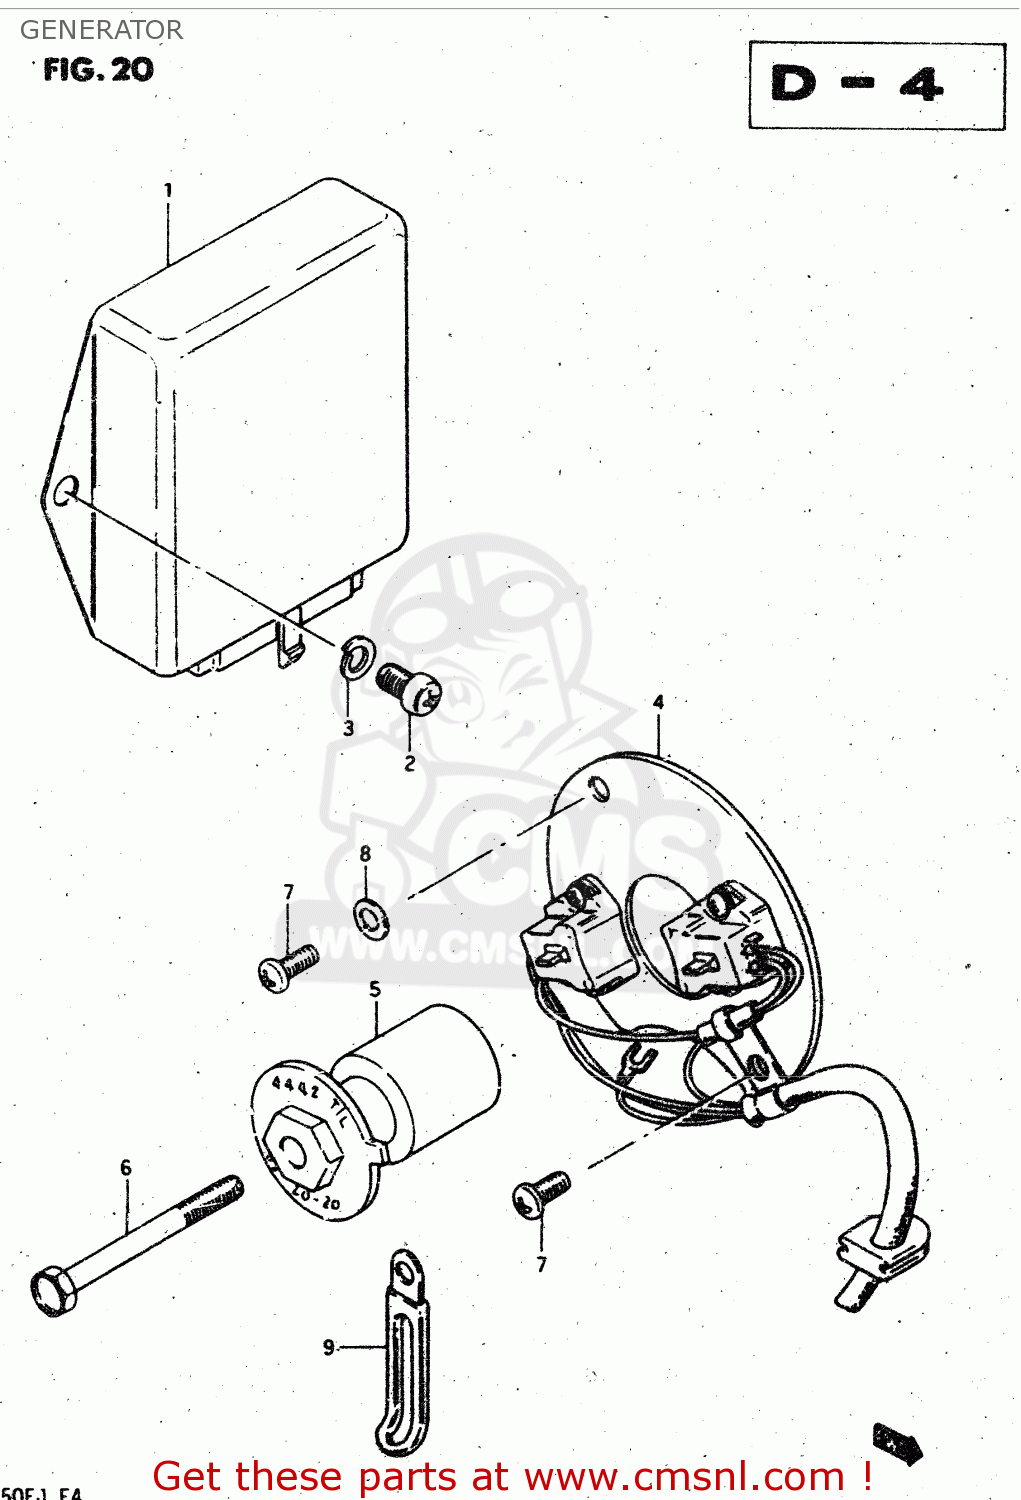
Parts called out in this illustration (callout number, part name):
1	GENERATOR ASSEMBLY
2	STATOR ASSEMBLY
3	ROTOR ASSEMBLY
4	SCREW
5	LOCK WASHER
6	BOLT 12X45
7	WASHER,LOCK 12
8	CLAMP,GENERATOR LEAD WIRE
9	SCREW
10	CLAMP,GENERATOR LEAD WIRE
11	SCREW
12	CLAMP L:35
